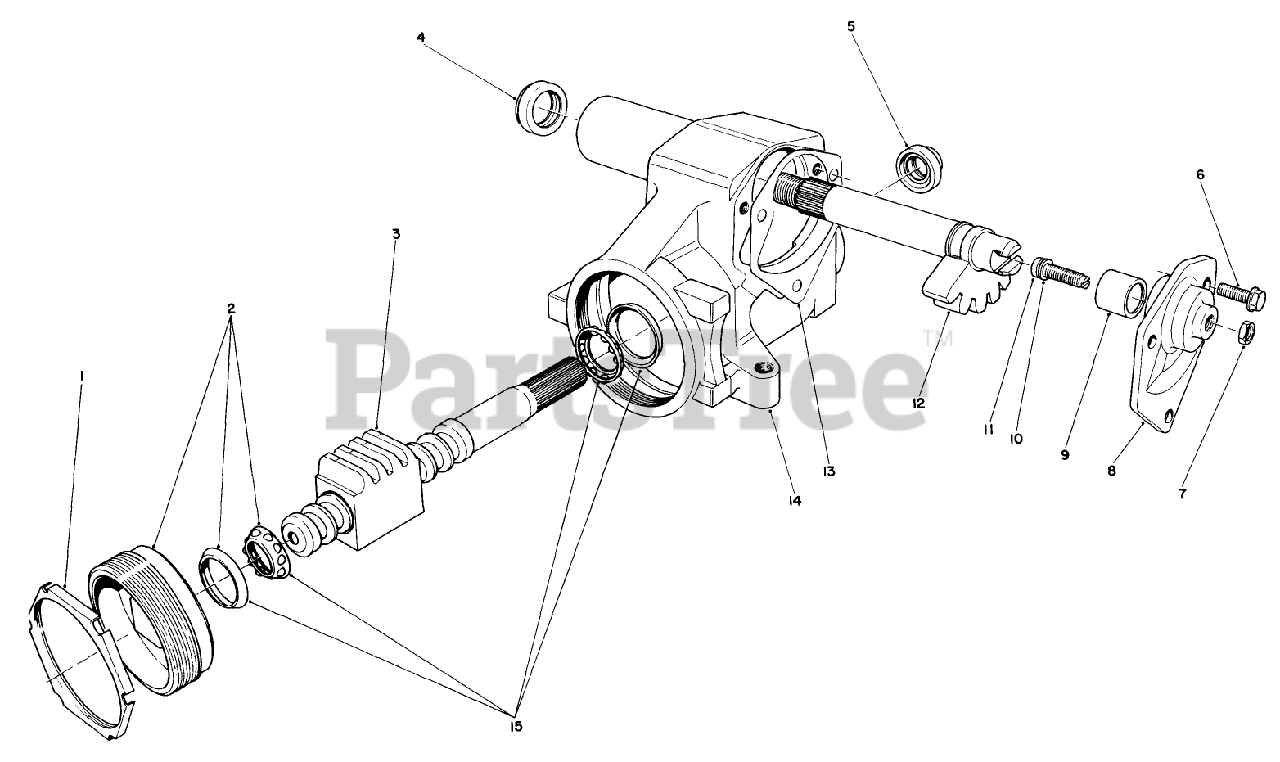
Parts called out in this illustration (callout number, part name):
1	Nut-Adjuster Lock
2	Adjuster Assembly
3	Steering Worm Assembly
6	Bolt-Flange Hex. Hd.
8	Side Cover Service Kit (Incl. Ref. #6, 9, 11 & 13)
10	Kit-Shim
11	Adjuster
12	Gear-Pitman Shaft
13	Gasket
14	Housing-Steering Gear
15	Assembly-Thrust Bearing
